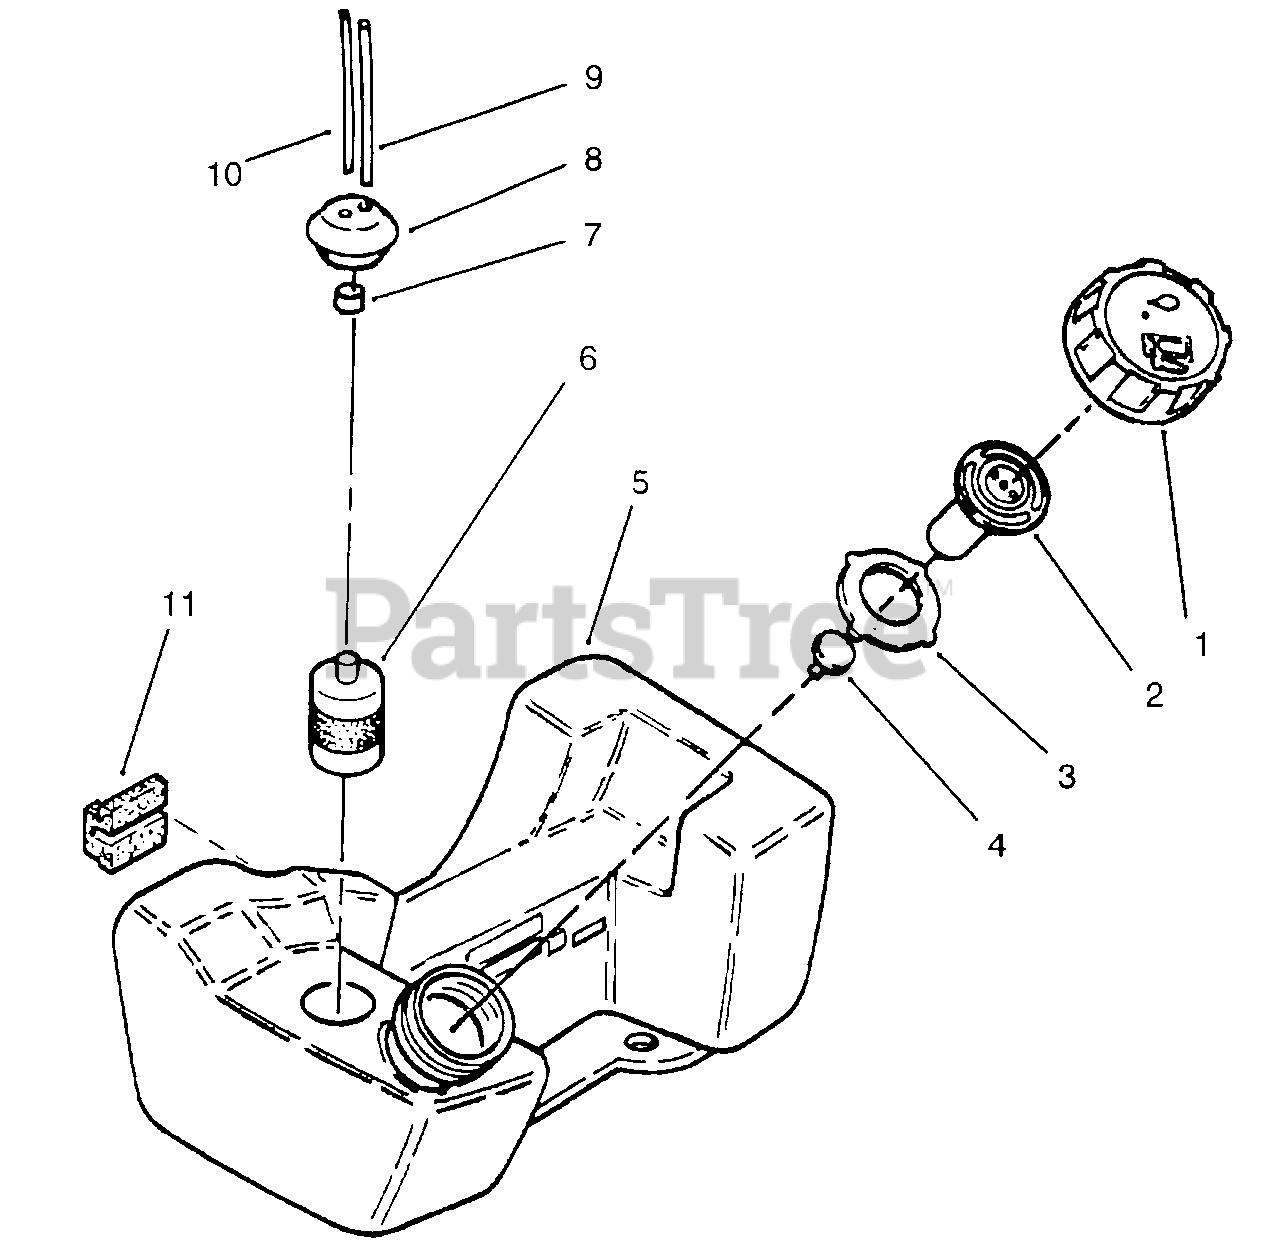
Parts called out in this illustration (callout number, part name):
1	Cap-Fuel
2	Valve-Breather
3	Gasket-Fuel Cap
4	Cap-Valve
5	Tank Assembly-Fuel (Incl. Ref. #1-4 & 10)
6	Filter Assembly-Fuel
8	Grommet-Fuel Tank
9	Tube-Fuel
10	Tube-Fuel
